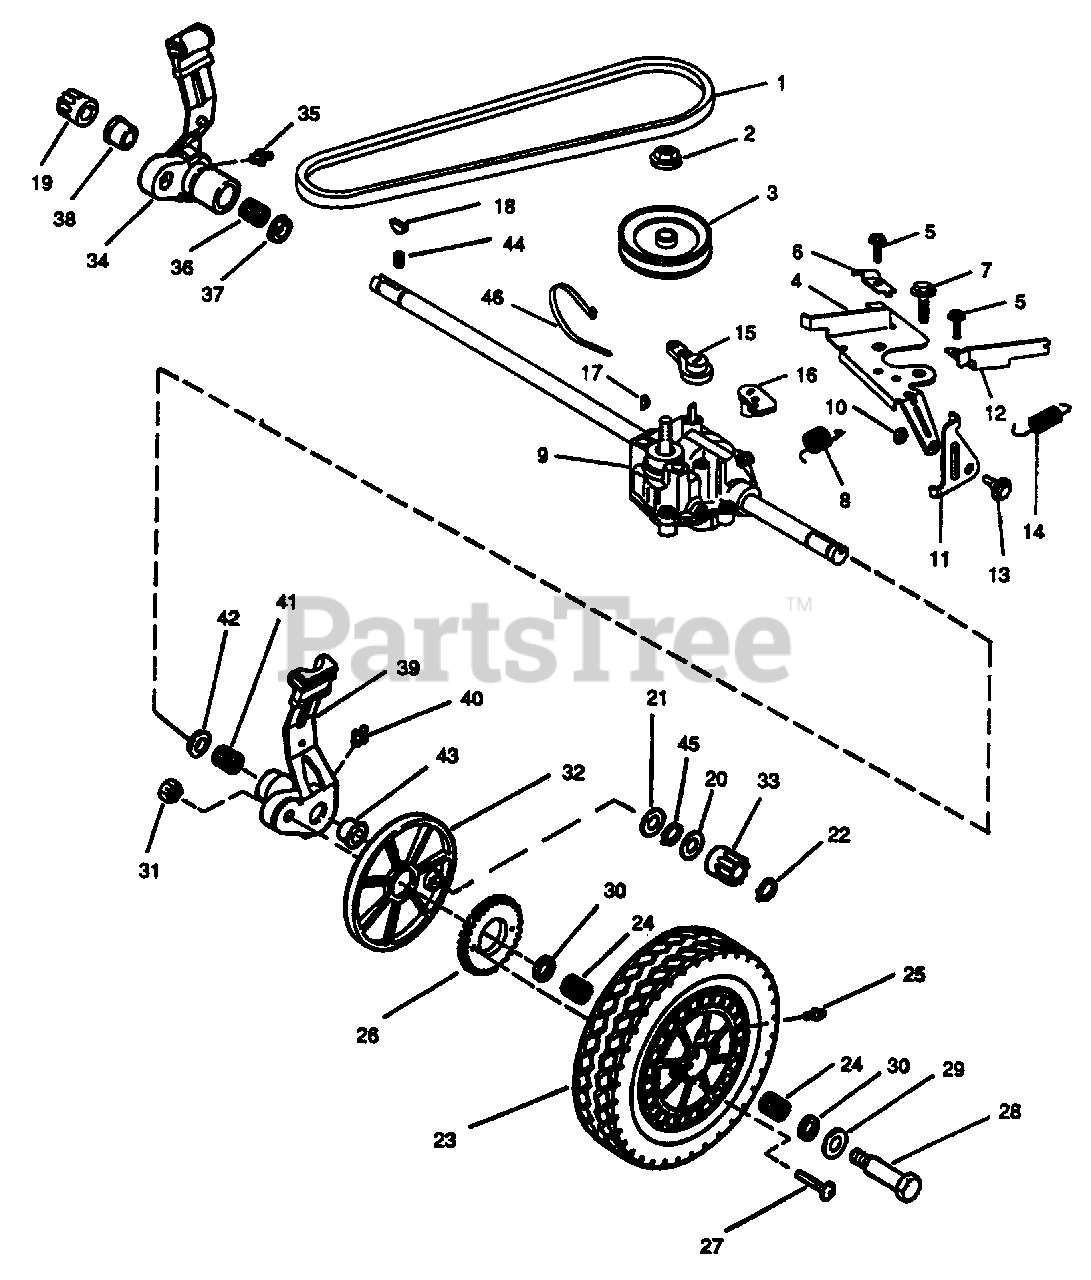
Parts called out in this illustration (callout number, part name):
1	V-Belt
2	Locknut
3	Transmission Pulley
4	Actuator Plate
5	Screw
6	Clamp
7	Screw-Plate to Transmission
8	Spring
9	Transmission
10	Nut
11	Arm-Transmission Engagement
12	Guide-Bell
13	Shoulder Bolt
14	Spring-Extension
15	Arm-Shift
16	Arm-Clutch
17	Key
18	Key-Pinion to Shaft
19	Drive Pinion R.H.
20	Thrust Washer
21	Thrust Washer
22	Retaining Ring
23	Wheel & Bearing Assy (Inc. 24-27)
24	Needle Bearing
25	Grease Fitting
26	Gear
27	Screw-Gear to Wheel
28	Shoulder Bolt-Rear Wheel
29	Flat Washer
30	Felt Washer
31	Nut-Wheel to Height Adjust Arm
32	Wheel Cover
33	Drive Pinion-L.H.
34	Height Adjust Arm-R.H. (Inc. 35-38)
35	Grease Fitting
36	Needle Bearing
37	Seal
38	Flange Bearing
39	Height Adjust Arm-L.H. (Inc. 40-43)
40	Grease Fitting
41	Needle Bearing
42	Seal
43	Flange Bearing
44	Spring-Pinion Key
45	Retaining Ring
46	Tie Strap
